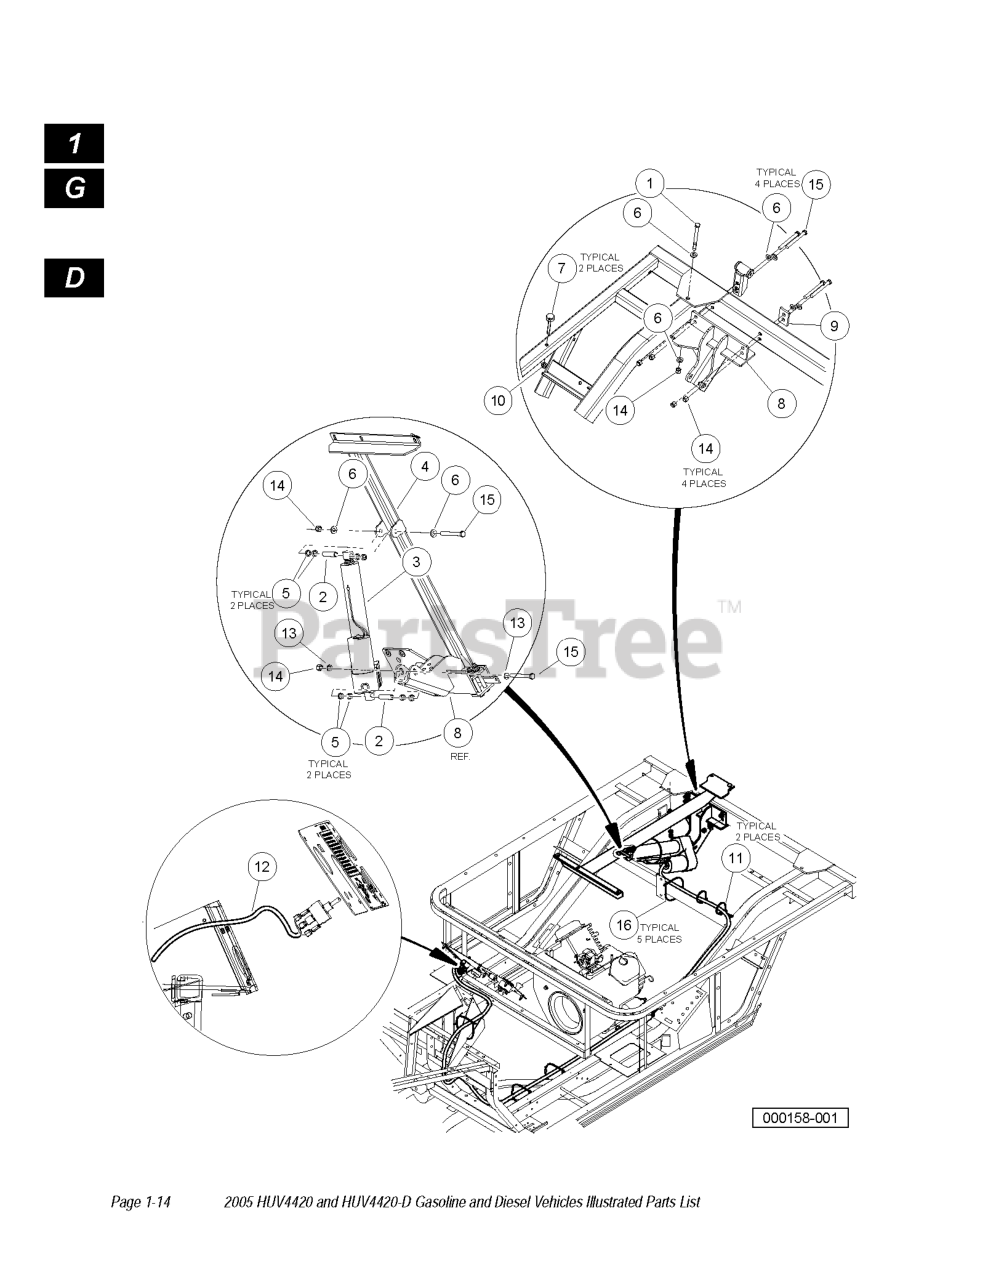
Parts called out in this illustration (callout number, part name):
1	BOLT HEX HEAD
2	BUSHING LONG
3	ACTUATOR ASSEMBLY, ELECTRIC
4	ASM, ACTUATOR ADAPTER
5	BODY SPACER
6	WASHER, 3/8 TYPE B HARD FLAT
7	BUMPER, BED, MTG, FRONT
8	WELDMENT, BRACKET, ACTUATOR
9	PLATE, BACK
10	LOCK NUT, FLG M8 X 1.25 NYLON
11	TIE WRAP, 8.00" WITH MOUNT
12	WIRE HARNESS, ELECTRIC LIFT
13	WASHER,LOCK,HEL SP 3/8 REG
14	LOCKNUT, 3/8-16 HEX
15	SCREW, 3/8-16 X 3.375
16	TIE WRAP, 8" NYLON
